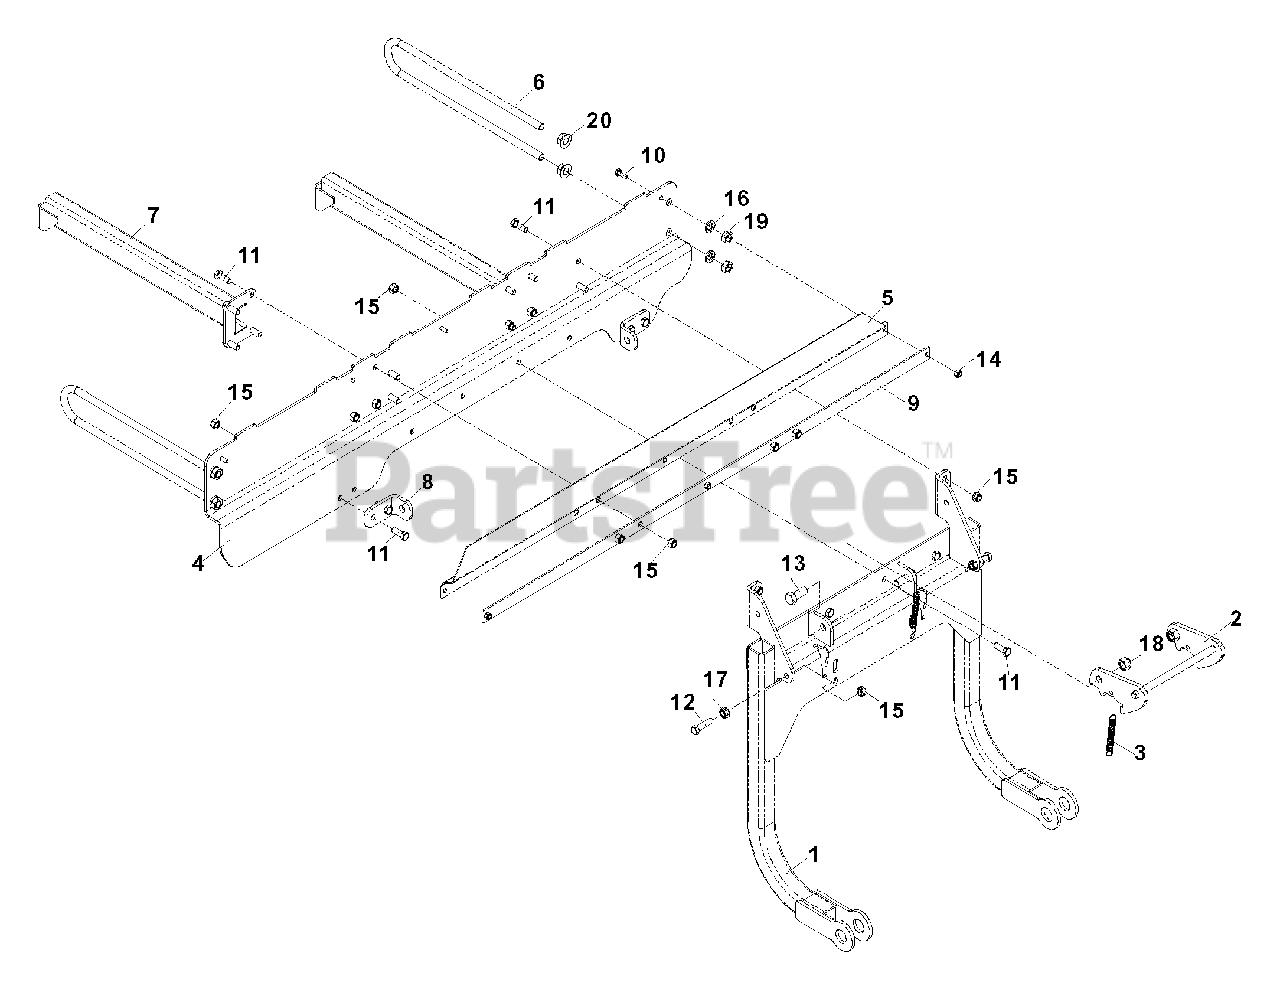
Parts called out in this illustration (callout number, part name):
4	MOUNT Z BRACE
5	SEAL, RUBBER
6	SUPPORT, OUTER
7	SUPPORT ARM
8	BRACKET, SUPPORT
9	SEAL STRAP
10	HCS, 1/4 -20 x 3/4
11	HCS, 3/8 -16 x 1
12	HCS, 3/8 -16 x 1 1/2
13	HCS, 1/2 -13 x 1 1/4
14	NUT, 1/4C, NYLOC
15	NUT, 3/8 C, NYLOC
16	WASHER, 1/2
18	NUT, 1/2C, NYLOC
19	NUT, 1/2, JAM
20	NUT, 1/2 -13, WHIZLOCK
